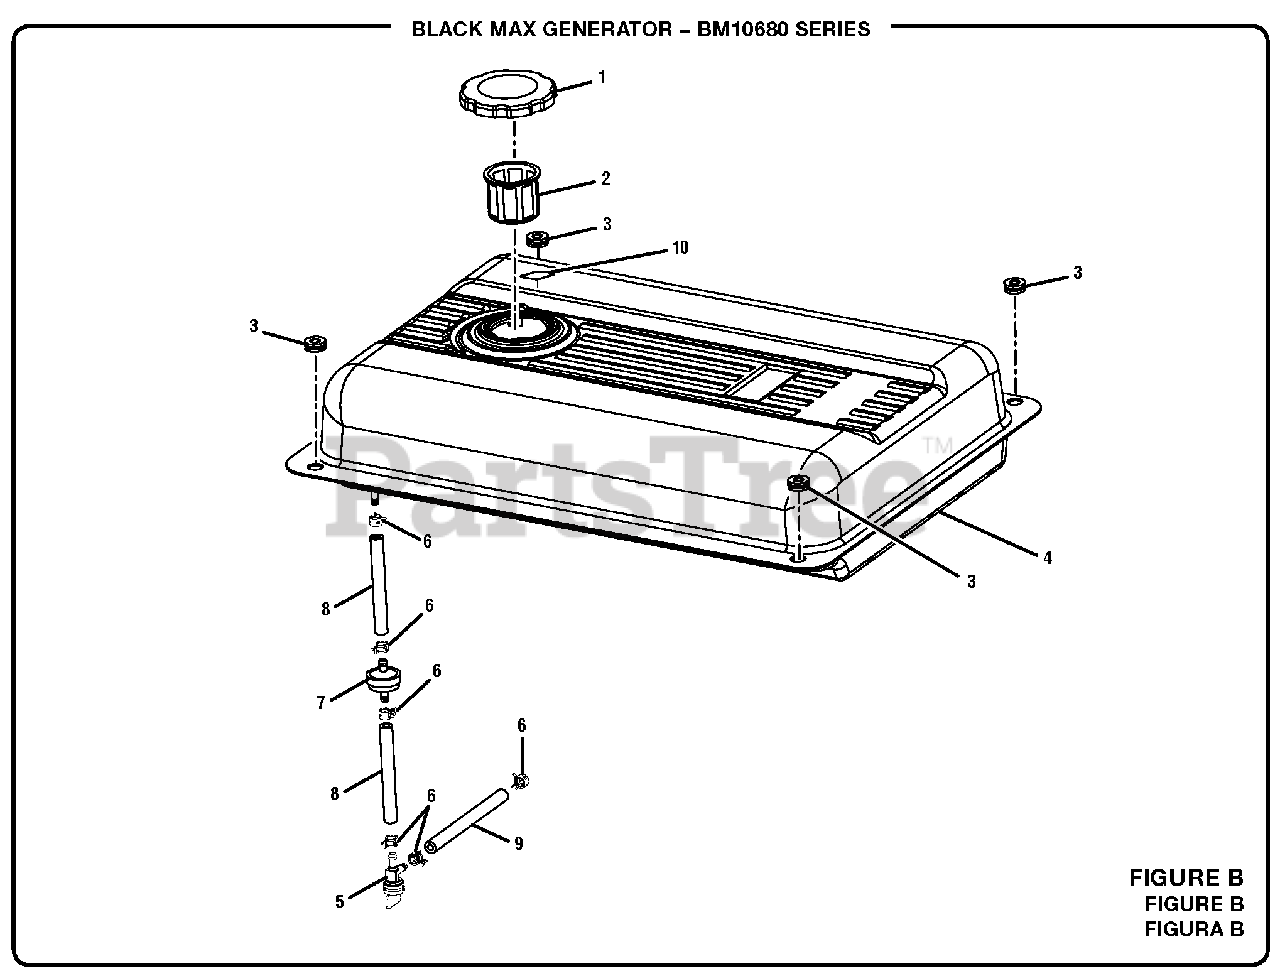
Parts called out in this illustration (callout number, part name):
1	Fuel Tank Cap
2	Fuel Tank Screen
3	Bushing w/Insert
4	Fuel Tank
5	Fuel Valve
6	Fuel Line Clamp (1/2 in)
7	Fuel Line Filter
8	Fuel Line (1/4 in)
9	Fuel Hose (5 mm)
10	E85 Label
